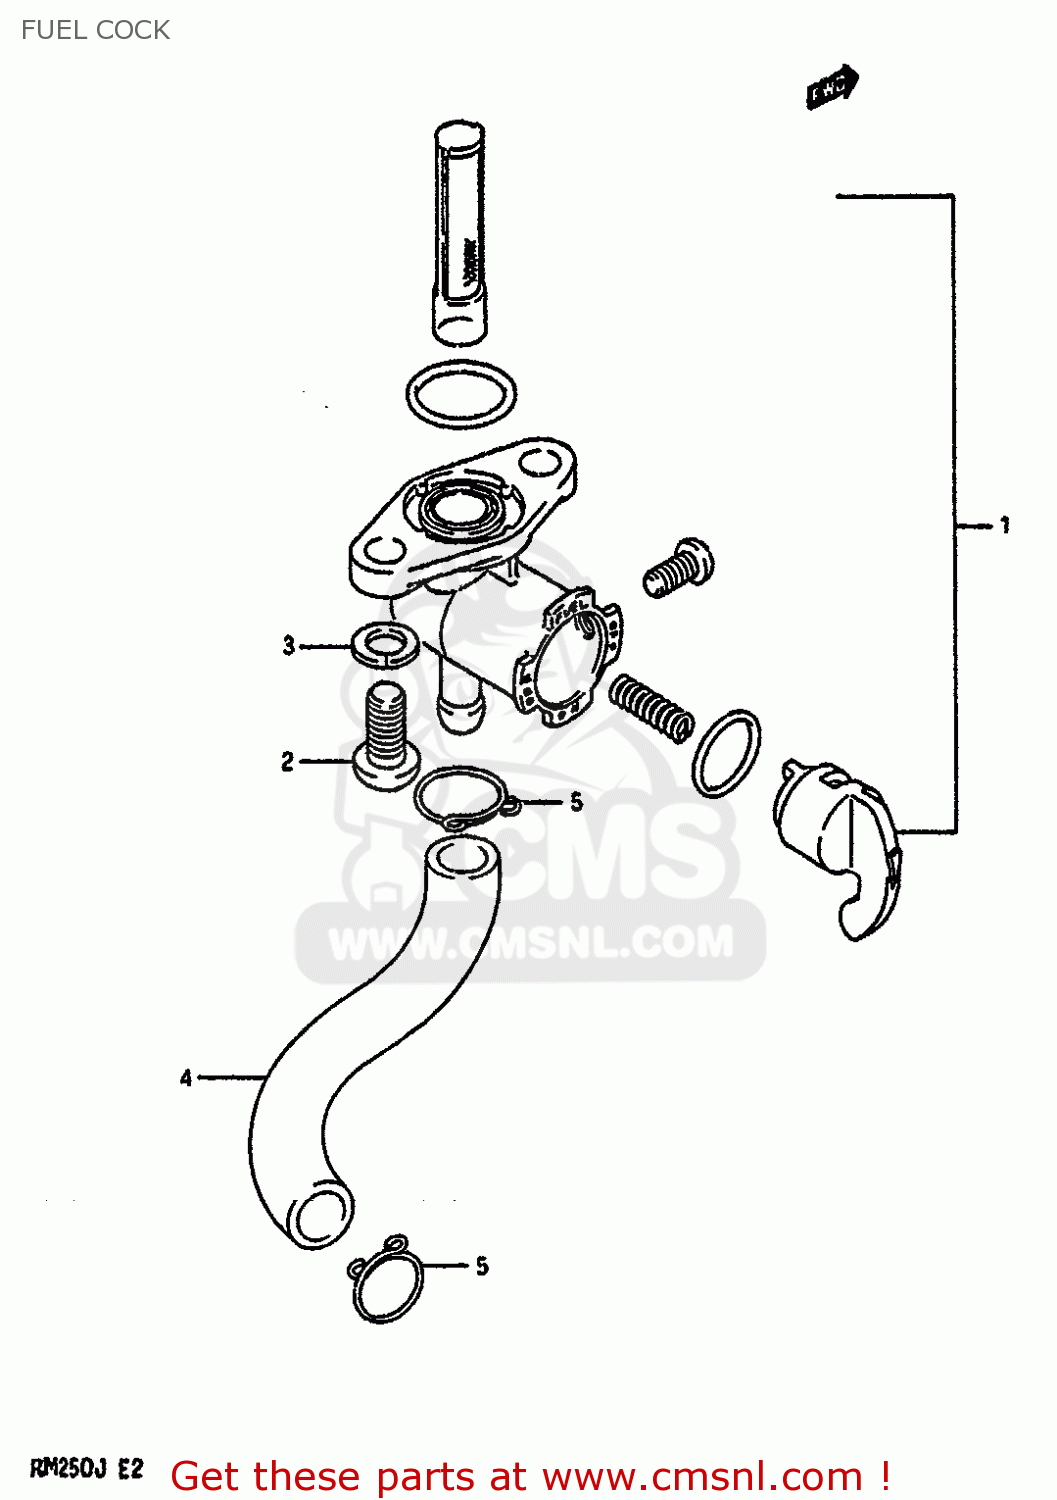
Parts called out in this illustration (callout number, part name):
1	COCK ASSEMBLY,FUEL
2	SCREW
3	WASHER,LOCK
4	HOSE
5	CLIP
